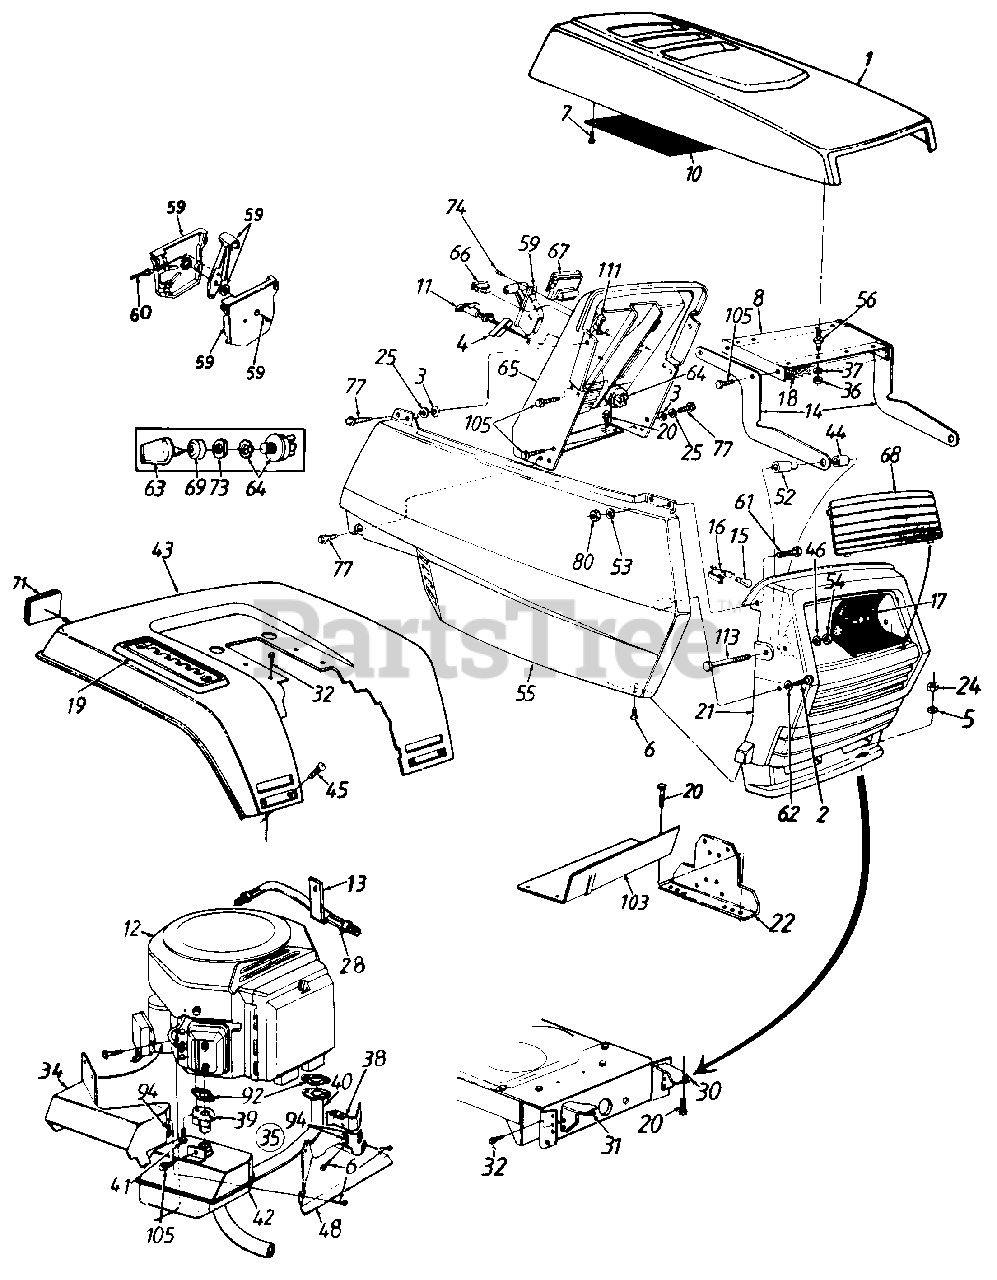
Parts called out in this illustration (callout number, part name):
3	Bolt Retainer 1/4" I.D.
4	RetainerClip
5	Fl-Wash. .34" I.D. x .68n
6	Truss Mach. AB-Tap Scr. #10 x .5" Lg.
7	Hex Wash Hd. AB-Tap Scr. #8 x .5 Lg.
8	Hood Plate
11	Choke Control 38" Lg.
12	Engine
14	Hood Hinge
15	Lamp
16	Twist Lock-Lamp Socket
17	Reflector-Headlight
21	Grille
24	Hex Nut 5/16-18 Thd.
25	Fl-Wash. 1/4" I.D. x .93" O.D.
28	Hydraulic Hose 13" Lg.
30	Grille Mount Brk't.-L.H.
31	Grille Mount Brk't.-R.H.
32	Hex Wash. Hd. AB-Tap Scr. 5/16 x .75" Lg.
34	Muffler Heat Shield
35	Muffler Ass'y. Comp.
36	Hex Nut 1/4-20 Thd.
37	Bell-Wash. .265" l.D. x .75"
38	Front Heat Shield Ext.
39	Inlet Tube Ass'y.
40	Formed Tube Ass'y.
41	Hex Bolt w/Washer
42	Muffler Sub Ass'y.
45	Carriage Bolt 1/4-20 x .50" Lg.
46	Fl-Wash. .328" I.D. x .68" O.D.
48	Front Heat Shield
52	Shld. Spacer .33" l.D.
53	Fl-Wash. .281" I.D. x .5" O.D.
54	Hex Cent. L-Nut 5/16-18 Thd.
55	Side Cover-R.H.
56	Double Ended Stud 1/4-20 Thd.
59	Throttle Control Box Ass'y.
60	Throttle Control Wire 35" Lg.
61	Hex Bolt 1/4-20 x .62" Lg.
62	Fl-Wash. .281" I.D. x .73" O.D.
64	Ignition Switch
65	Dash Panel
66	Light Switch
67	Ammeter
68	Lens
69	Ignition Switch Cap
71	Reflector
73	Ignition Switch Nut
74	Truss Mach. AB-Tap Scr. #10 x .5" Lg.
77	Hex Wash. Hd. Tap Scr. 1/4 x .75" Lg.
80	Hex L-Nut 1/4-20 Thd.
92	Gasket
94	Speed Nut #10-24 Thd.
103	Gasoline Tank Support
105	Hex Tap Scr. 1/4-20 x .5" Lg.
111	Speed Nut 1/4-20 Thd.
113	Hex Bolt 5/16-18 x 2.75n
